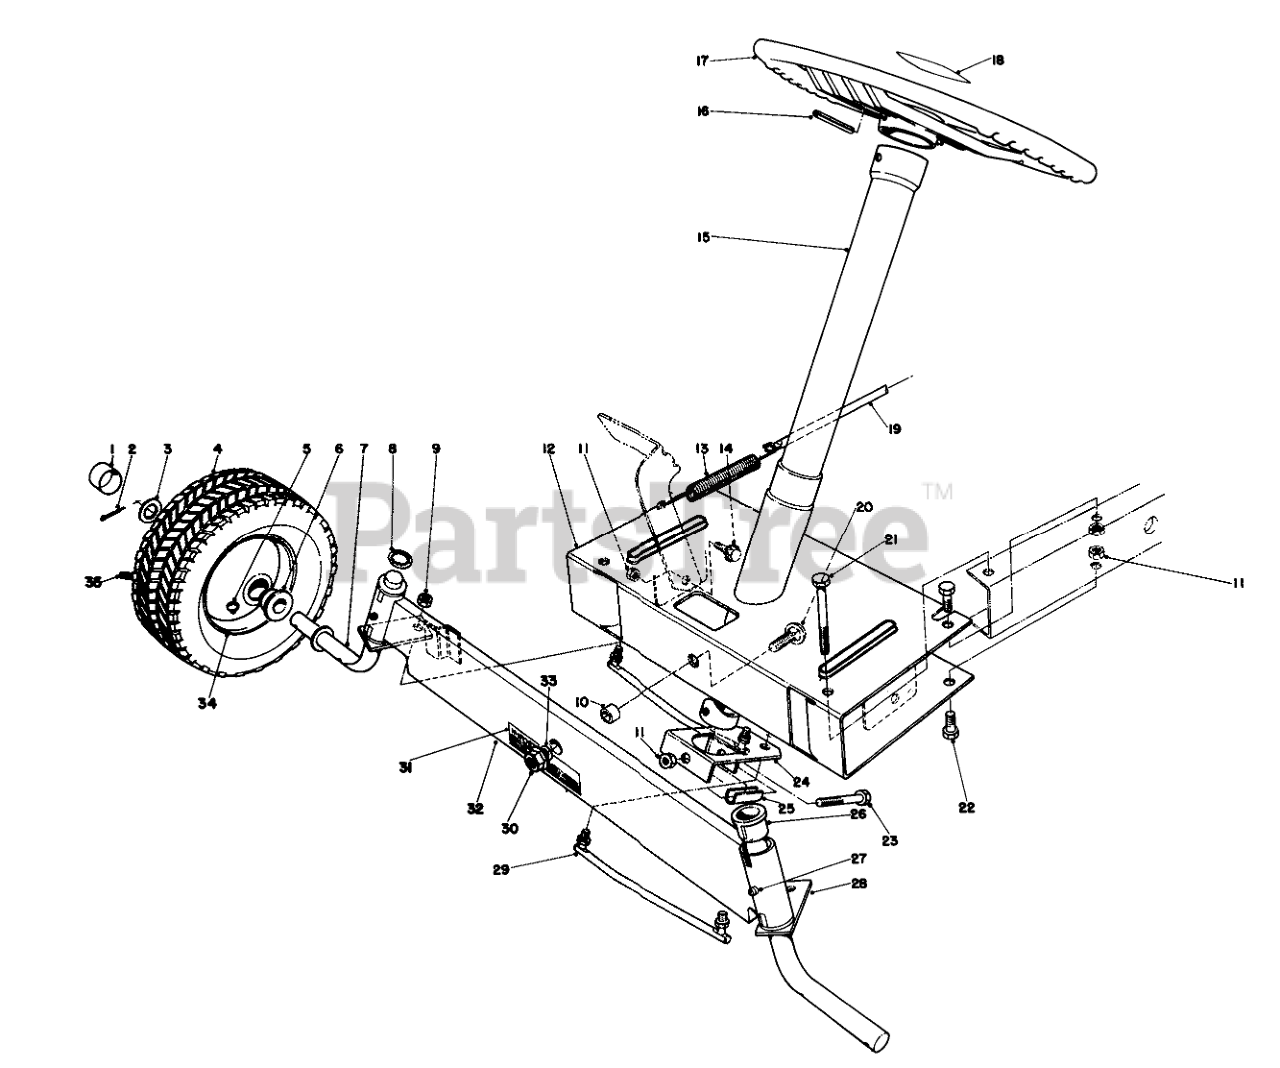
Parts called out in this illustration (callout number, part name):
1	Hub Cap
2	PIN-COTTER
3	WASHER-FLAT
4	Tire Turf King
5	FITTING-GREASE
6	BUSHING
7	SPINDLE WA RH
8	RING-RETAINING
9	NUT-LOCK NI
10	FRONT AXLE SPACER
11	NUT-LOCK, CONE
12	Front Frame
13	BRAKE TENSION SPRG O
14	SCREW-SHOULDER
15	Steering Tube
16	PIN-ROLL
17	Steering Wheel
18	Decal
19	Brake Rod
20	SCREW-CARR
21	SCREW-HH
22	SCREW-HH
23	SCREW-HH
24	Lever Steering
25	Spacer-Steering Tube
26	BUSHING
27	GREASE FITTING
28	Spindle L.H.
29	TIE ROD ASM
30	NUT-HF
31	Decal-Warning
32	Front Axle
33	WASHER-THRUST
35	STEM-VALVE
